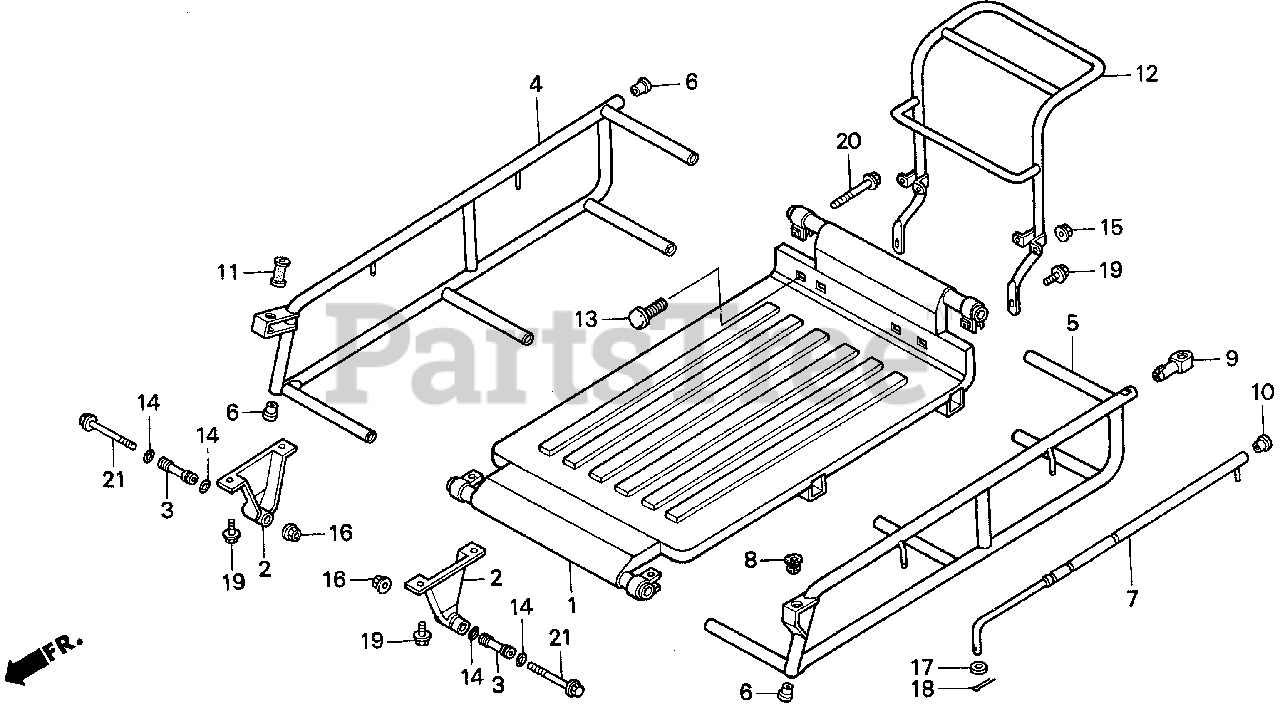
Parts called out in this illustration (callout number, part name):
1	BODY, CARRIER *NH35M* (CLOUD SILVER METALLIC)
2	BRACKET, CARRIER
3	COLLAR, CARRIER BRACKET
4	PIPE, R. GUIDE
5	PIPE, L. GUIDE
6	CAP, L. GUIDE PIPE *NH1* (BLACK)
7	BAR ASSY., FR.
8	COLLAR, FR. BAR *NH1* (BLACK)
9	HOLDER, FR. BAR
10	CAP, FR. BAR
11	BUSH, CARRIER GUIDE
12	PIPE, ENGINE GUARD
13	BOLT, SPECIAL (9X15)
14	O-RING (16MM)
15	NUT, FLANGE (8MM)
16	NUT, FLANGE (12MM)
17	WASHER, FLAT (12MM)
18	PIN, COTTER (2.5X22)
19	BOLT, FLANGE (8X16)
20	BOLT, FLANGE (8X32)
21	BOLT, FLANGE (12X70)
